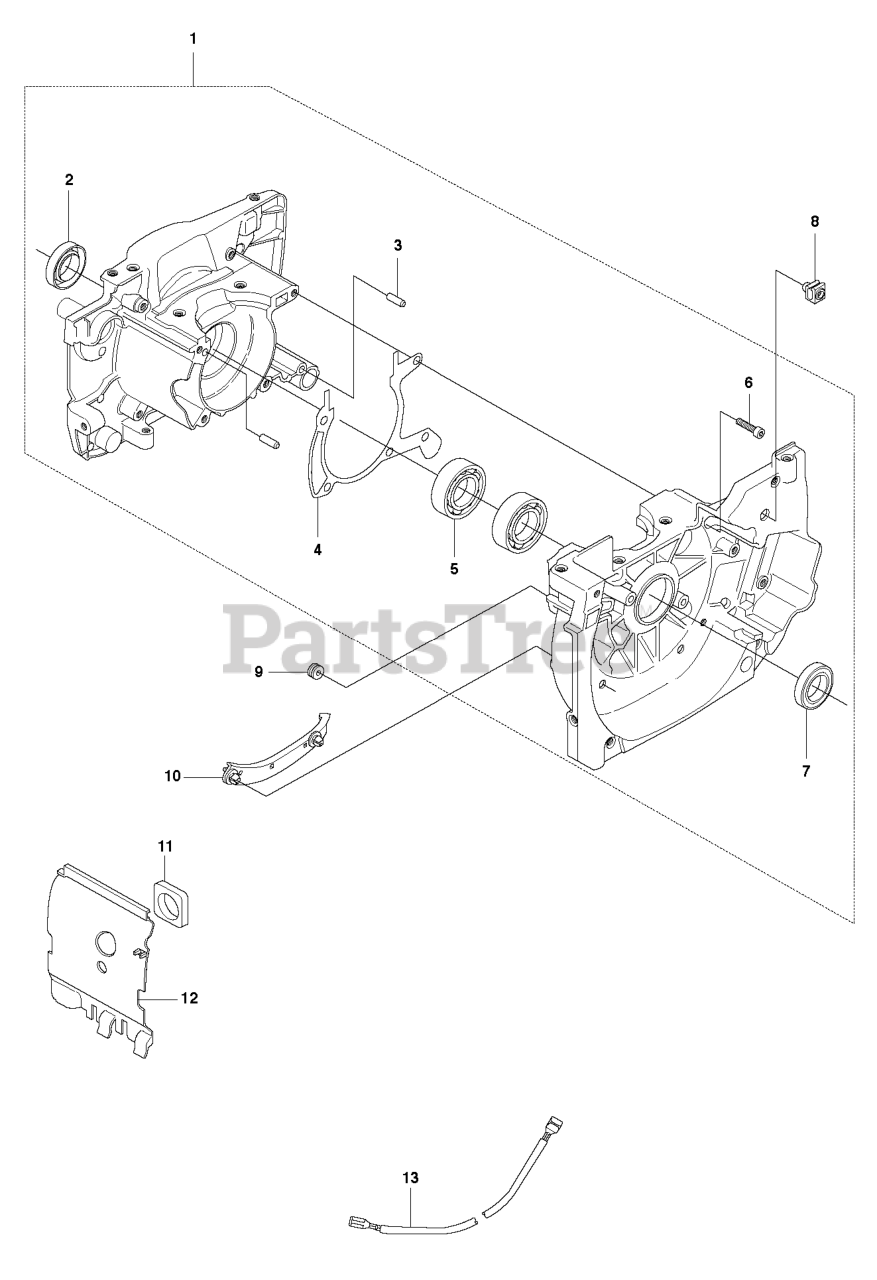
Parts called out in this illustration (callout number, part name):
2	SEALING RING
3	PIN 5X14
5	BALL BEARING
6	SCREW MC6S 5X20
8	CABLE SOCKET
9	FUEL TANK BUSHING
11	SEAL
12	AIR CONDUCTOR
13	SHORTING LEAD
